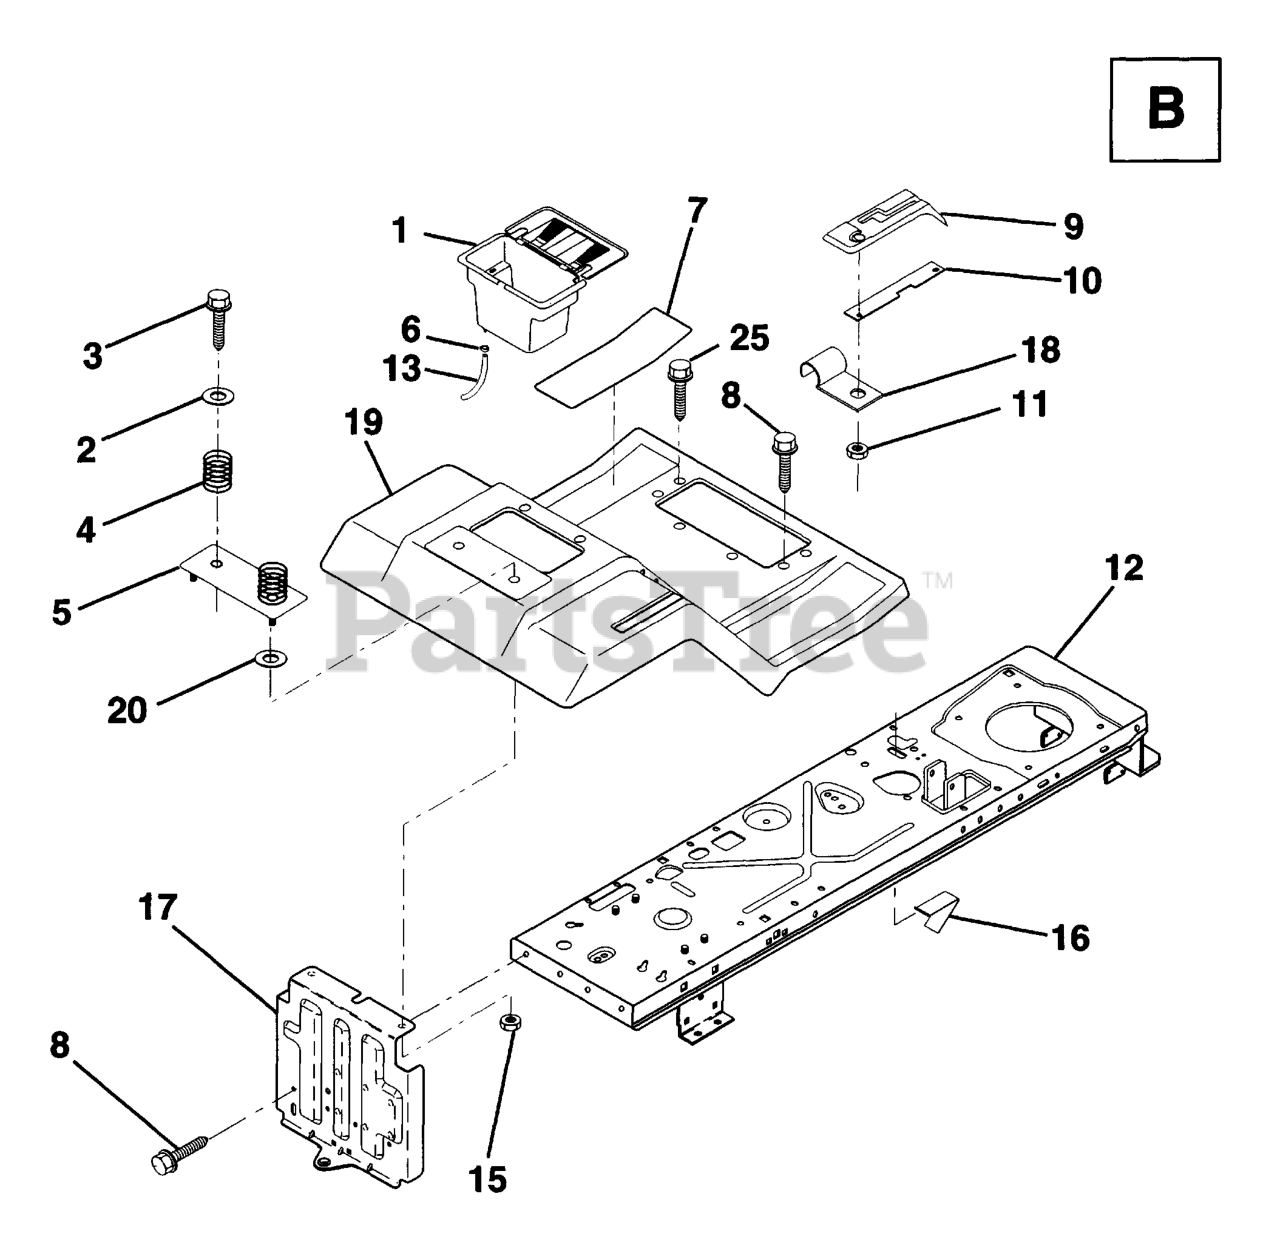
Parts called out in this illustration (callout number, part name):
1	CASE BATTERY
2	WASHER
3	SCREW
4	SPRING COMPRESSION
5	PLATE ASM BATTERY
6	HOSE CLAMP T
7	FOOTREST PAD
8	SCREW.THDROL.5/16-18X3/4.TTY
9	CONSOLE,SHT CONTR
10	BAR, SHIFT LOCK
11	NUT.PUSH.3/16
13	TUBE BATTERY DRAIN
15	LOCKNUT
16	SWITCH ACTUATOR
18	CLIP,INSULATOR
19	FENDER/FOOTREST
20	WASHER
25	SCREW
